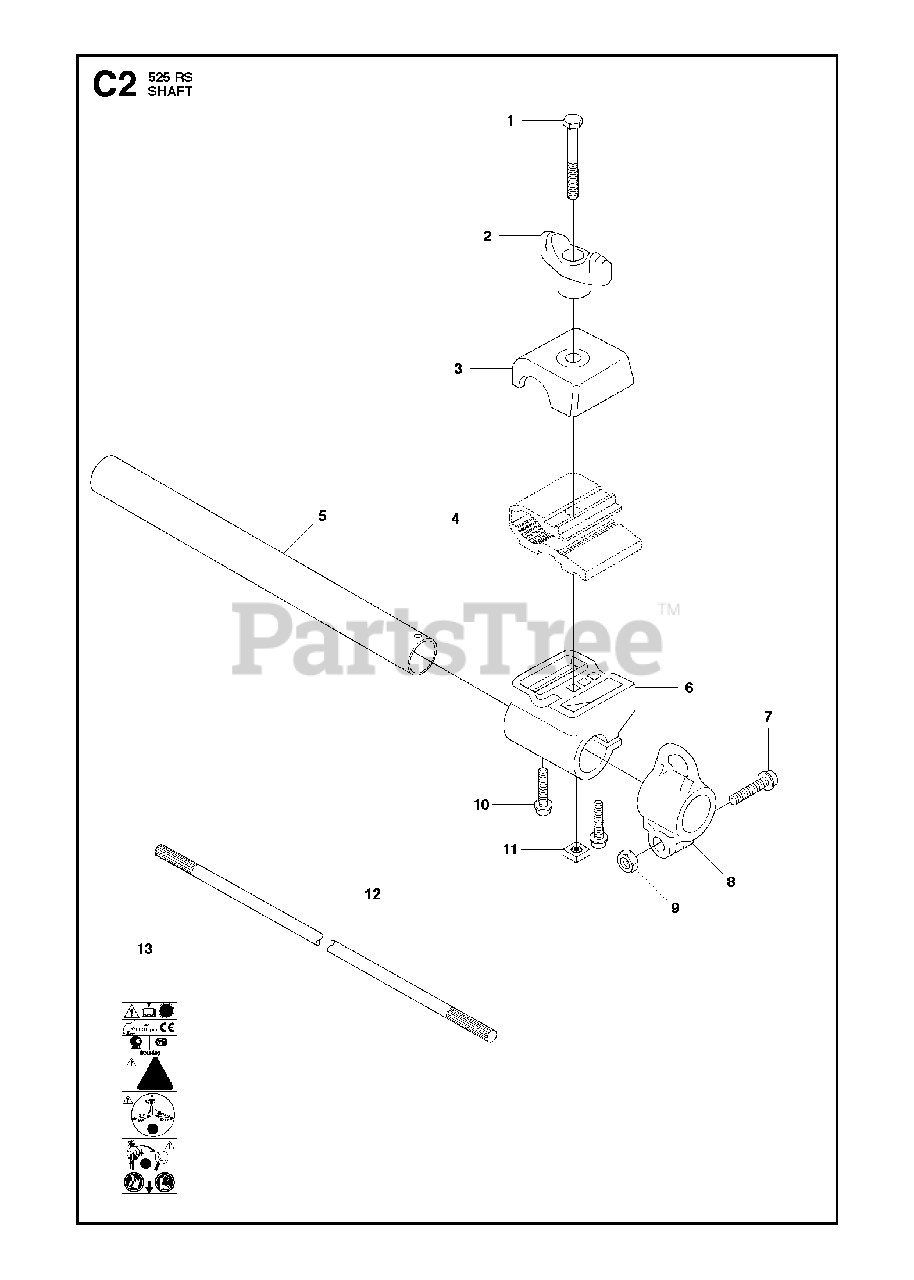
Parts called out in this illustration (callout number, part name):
1	%SCREW
4	HOLDER
7	SCREW
8	HARNESS HOLDER
12	DRIVESHAFT
13	WARNING DECAL
